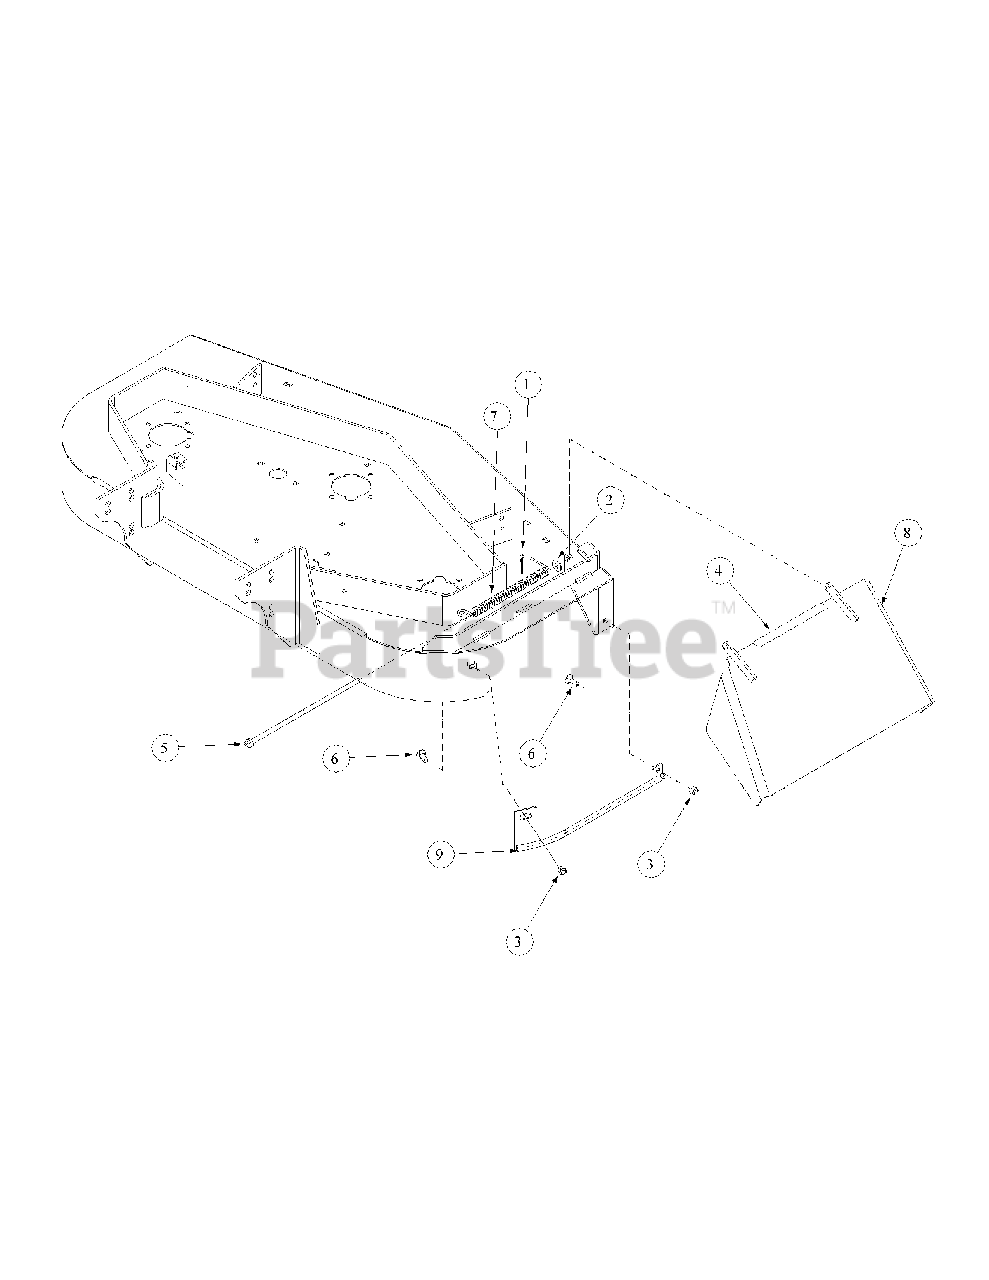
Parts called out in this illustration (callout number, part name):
1	Cotter Pin, 5/32 x 1" Lg. Zinc
2	Flat Washer, 3/8 Zinc
3	Lock Nut, Nylon Insert, 3/8-16
4	Decal, Cut LIne
5	Pin Deflector Assembly, Weldment
6	Carriage Bolt, 3/8-16 x 2
7	Torsion Spring
8	Chute Assembly
9	Stiffner Assembly, 48
